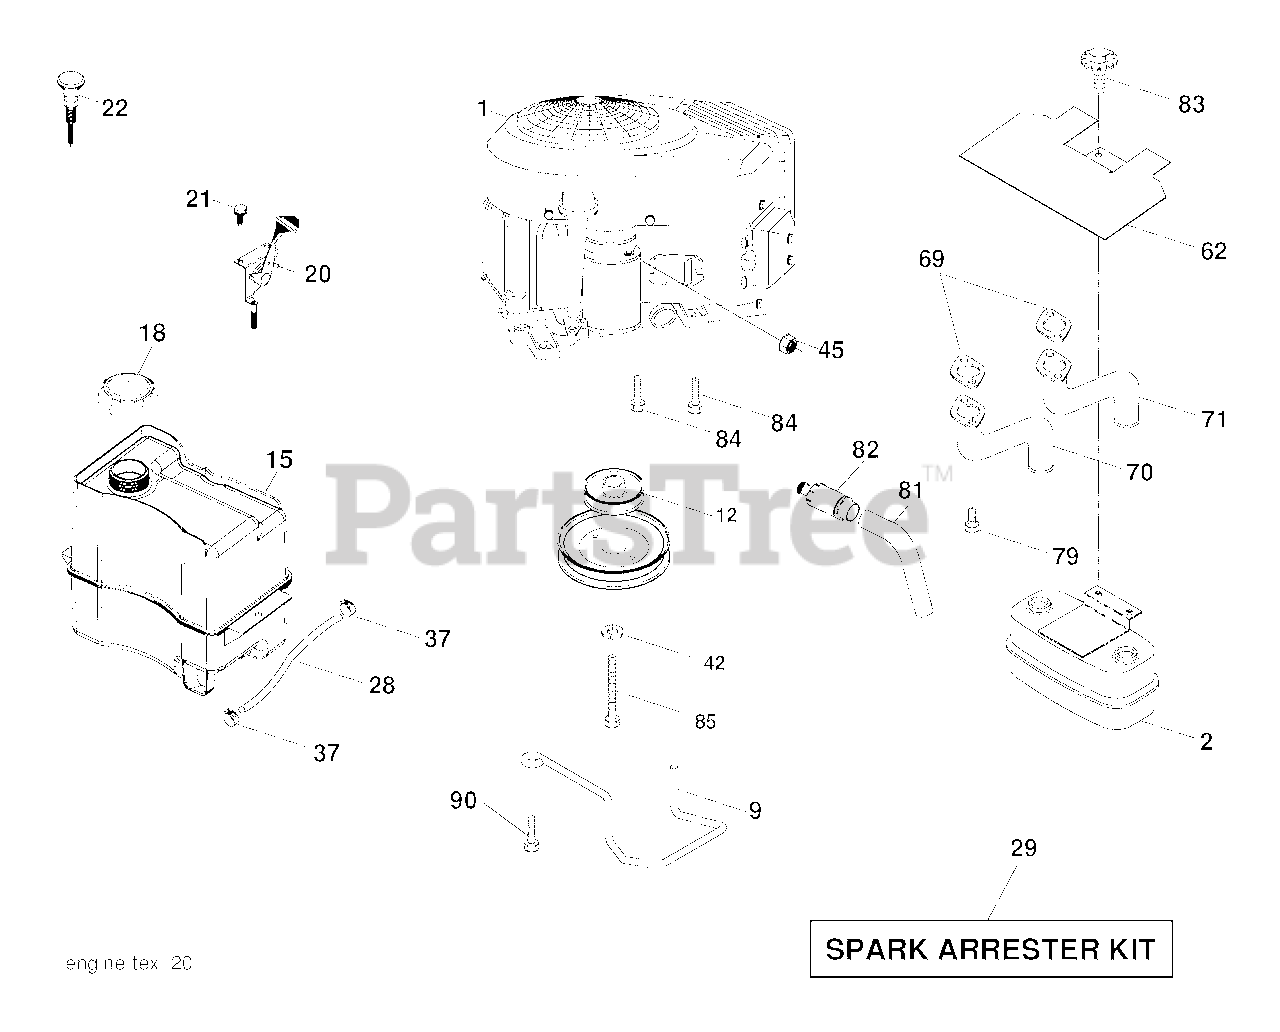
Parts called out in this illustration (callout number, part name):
2	Muffler
9	Keeper Belt Engine
12	Pulley Engine
15	Tank Fuel 3.0
18	Cap Asm
20	Control Throttle
21	Screw 10 x 3/4 Single Lead-Hex
22	Control Choke
28	Fuel Line
29	Spark Arrester Kit
37	Clamp Hose
42	Washer Lock 7/16
45	Nut Keps Hex 1/4-20 unc
62	Shield Heat Muffler
69	Gasket
70	Exhaust Tube RH
71	Exhaust Tube LH
79	Screw Socket Head 5/16-18 x 1
81	Tube Drain Oil Easy
82	Plug Drain Oil
84	Screw 3/8-16 x 1-1/4
85	Bolt Hex 7/16-20 x 4 x 5 Ga.-1.5
87	Bolt 5/16-18 x 3/4
90	Screw 3/8-16 x 1
